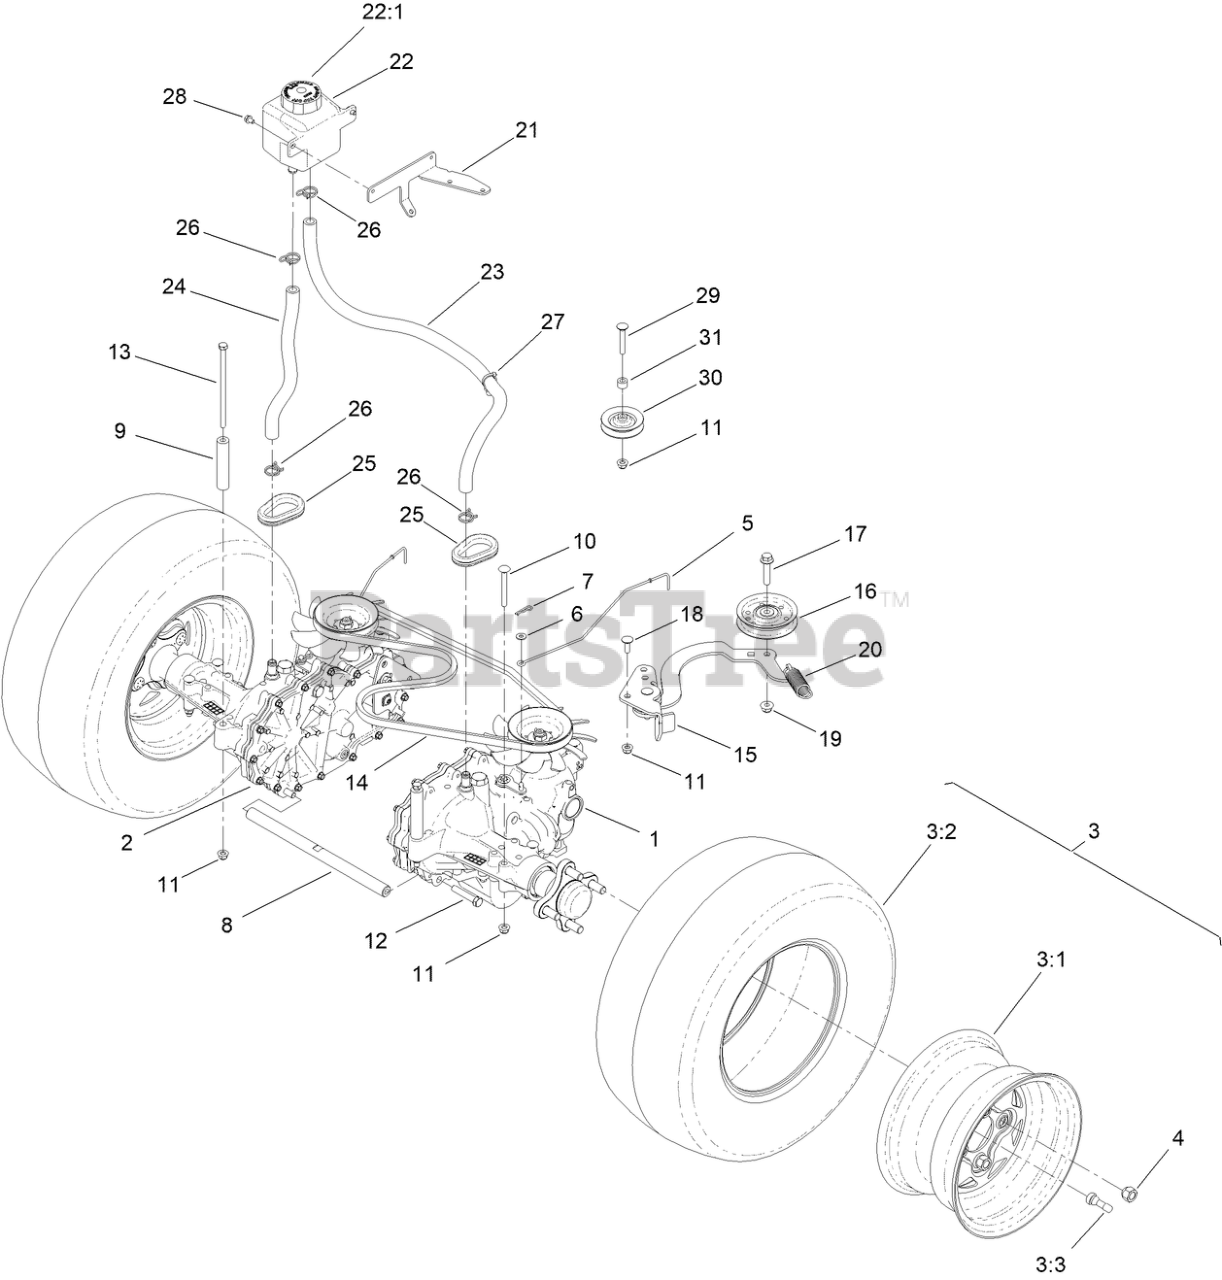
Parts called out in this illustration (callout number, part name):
1	TRANSMISSION, ZT-2800 LH
2	TRANSMISSION, ZT-2800 RH
3	WHEEL AND TIRE ASM
3:1	RIM-10"
4	NUT-LUG
5	ROD-BYPASS
6	WASHER-FLAT
7	PIN-COTTER
8	SHAFT-CROSS, HYDRO
9	SPACER - TRANSMISSION
10	SCREW-CARR
11	NUT-HF, NI
12	SCREW-HH W/LOCTITE
13	SCREW-HH
14	BELT-V
15	IDLER ARM ASM
16	PULLEY-IDLER, FLAT
17	SCREW-HHF
18	BOLT-CARR
19	NUT-HF, NI
20	SPRING-EXTENSION
21	BRACKET - EXPANSION TANK
22	TANK-HYD
22:1	CAP-RESERVOIR, HYD
23	HOSE-HYDRO
24	HOSE-OVERFLOW
25	GROMMET
26	CLAMP-HOSE
27	CLIP-TIE
28	SCREW-HWH
29	BOLT-CARR
30	PULLEY-IDLER
31	SPACER
